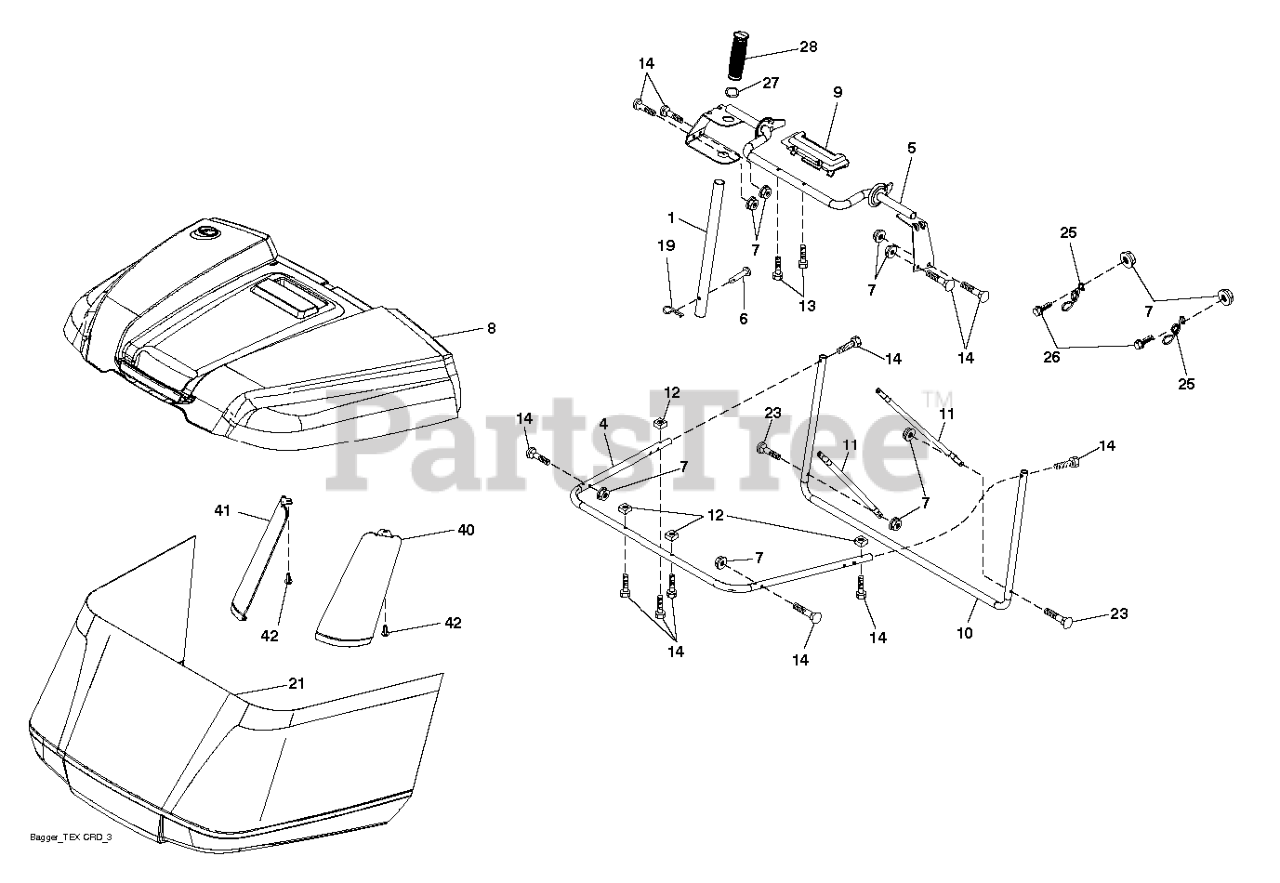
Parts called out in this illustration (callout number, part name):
1	TUBE.HANDLE.BAGGER.CRD/SRD.BLA
4	SUBASM.TOP.TUBE.TEX.CRD
5	FRAME.ASM.TOP.BAGGER.SRD
6	RIVET,DRILLED
7	NUT T
8	BAGGER.TOP.SUB.ASSEM.SRD
9	INSERT.HANDLE.BAGGER.(2 2)
10	FRAME FRAME.FRONT.TEX.CRD
11	BRACE BRACE SIDE TUBE
12	NUT.SQUARE.1/4
13	SCREW.1/4X1.150.HXWSH
14	BOLT.SHOULDER.HX.WSH.1/4X1.150
19	PIN.COTTER.5/16.BOW TI
25	SPRING.LATCH.BAGGER.SRD
26	SCREW HEX CRT
27	RB GROMMET.RUBBER.SRD
28	GRIP.HANDLE.BLACK
42	CLIP CHRISTMAS TREE CLIP
